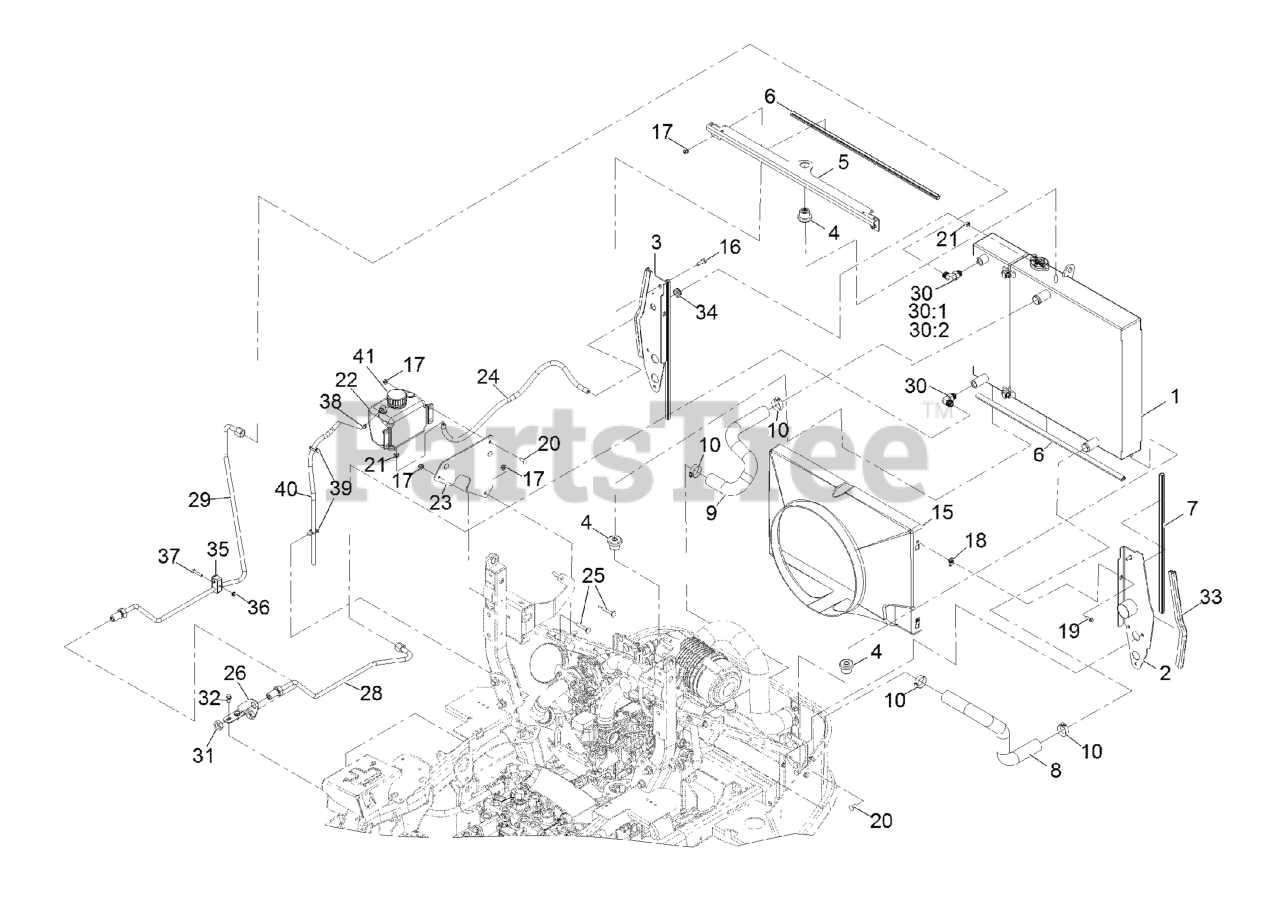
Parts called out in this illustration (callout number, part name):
1	COOLING ASM
2	SUPPORT-RADIATOR, LH
3	SUPPORT-RADIATOR, RH
4	MOUNT-ISOLATOR
5	BRACKET-COOLING, TOP
6	SEAL-BULB
7	SEAL-BULB
8	HOSE-RADIATOR, LOWER
9	HOSE-RADIATOR, UPPER
10	CLAMP-HOSE
15	SHROUD-FAN
16	SCREW-HHF
17	NUT-HF, NI
19	SCREW-HWH
20	SCREW-CARR
21	CLAMP-HOSE
22	TANK-OVERFLOW, W/CAP
23	BRACKET-BOTTLE
25	BOLT-CARR
26	BRACKET-BULKHEAD
28	HYDRAULIC TUBE ASM
29	HYDRAULIC TUBE ASM
30	FITTING-ELBOW, 90 DEG
30:1	O-RING
30:2	O-RING
31	NUT-BULKHEAD
32	Screw-HWH 5/16-18 X 3/4 Tf
33	SEAL-BULB
34	GROMMET
35	CLAMP-TWIN
37	SCREW-HH
38	CLAMP-HOSE
39	CLIP-TIE
40	HOSE-FUEL
41	CAP-W/TETHER
